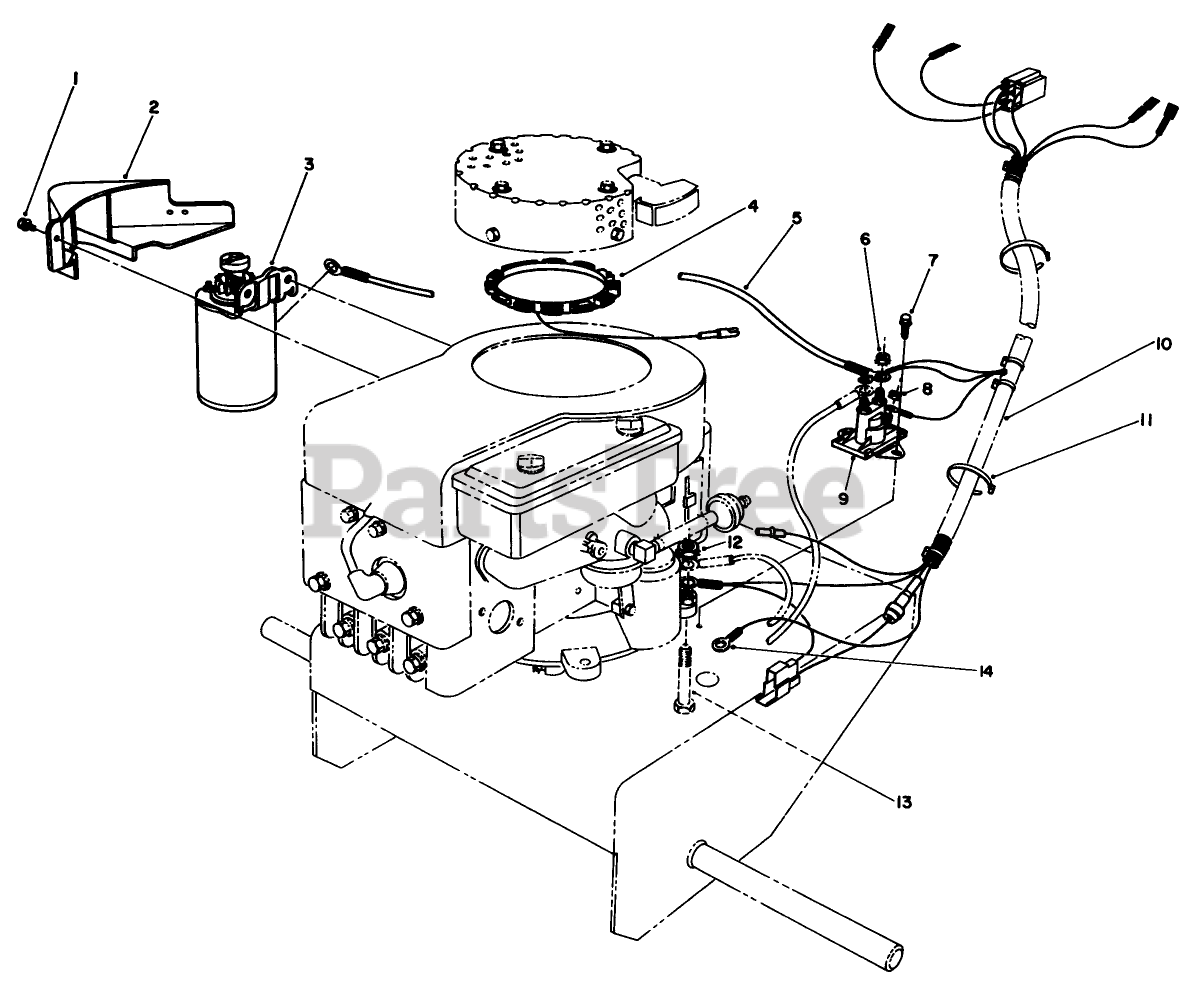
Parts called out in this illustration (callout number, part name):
1	Screw
2	Cover-Starter
3	Motor-Starter (Incl. Ref. #1 & 2)
4	Alternator
5	WIRE-SOLENOID/STARTER
6	NUT-KEPS
7	SCREW
8	NUT-KEPS
9	Solenoid
10	16 HP WIRE HARNESS
11	TIE-CABLE
12	NUT-LOCK, CONE
13	SCREW-HH
14	Terminal
